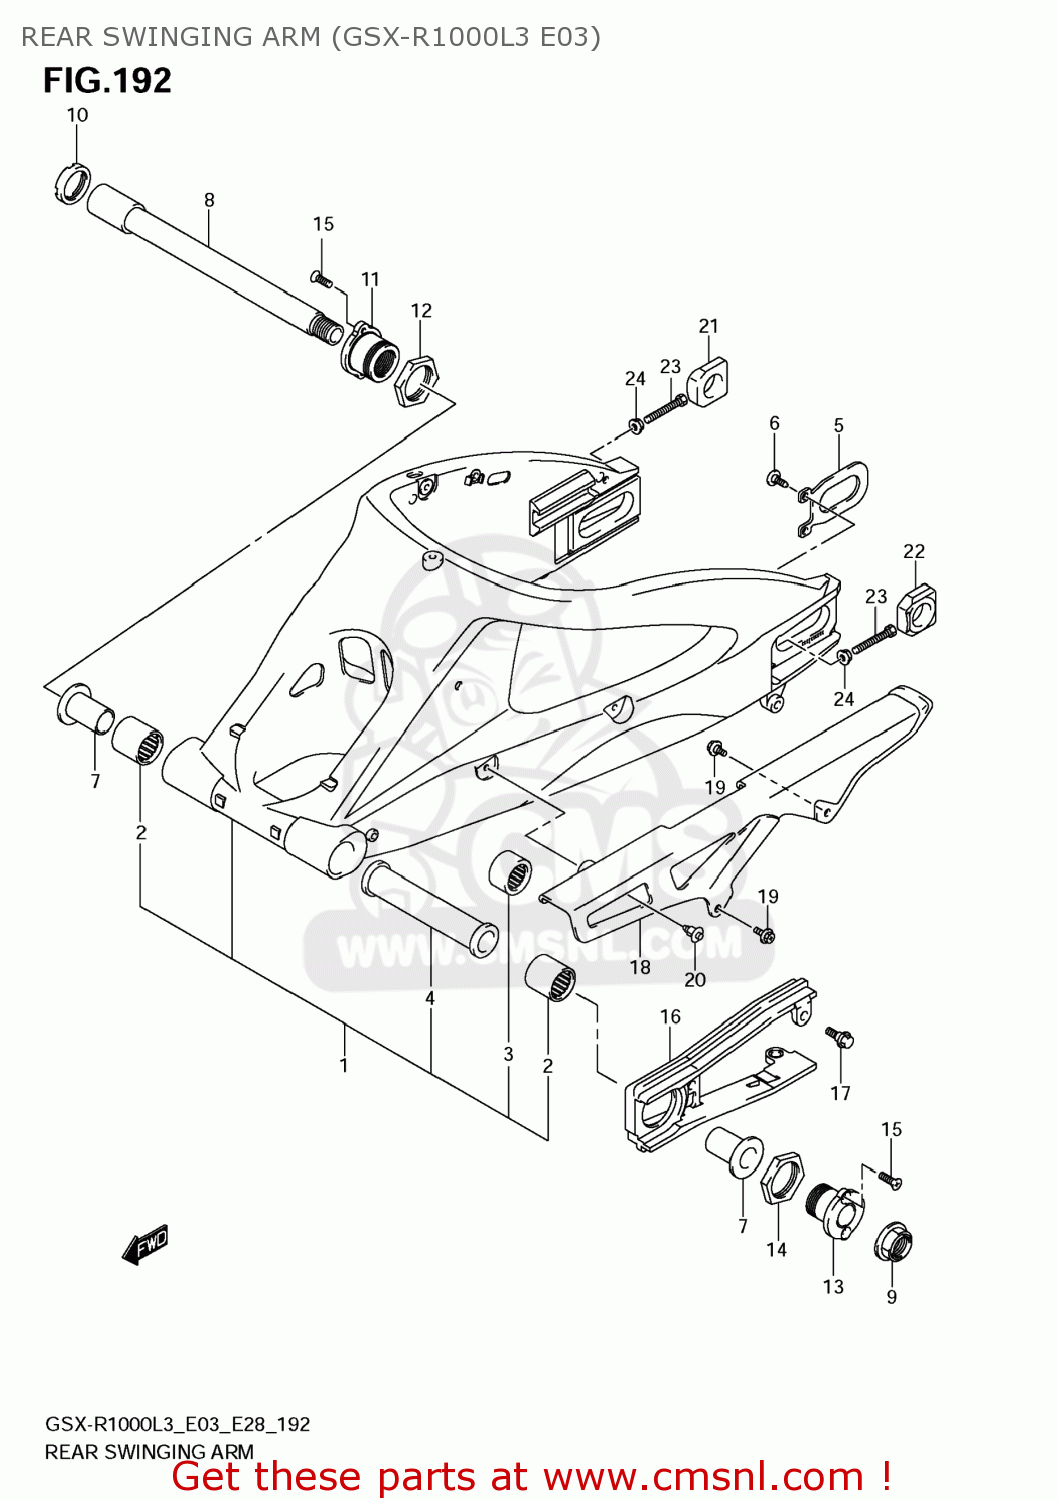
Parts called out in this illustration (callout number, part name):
1	SWINGINGARM ASSY,RR
2	BEARING(27X35X35)
3	BEARING(20X27X30)
4	SPACER,RR SWG PVT CTR
5	PLATE,RR SWING ARM BRKT
6	SCREW(6X12)
7	SPACER,RR SWGARM PIVOT BEARING
8	SHAFT,RR SWINGINGARM PIVOT
9	NUT
10	NUT,RR SWGARM PIVOT BOLT
11	BOSS,RR SWINGINGARM PIVOT,R
12	NUT,RR SWGARM PIVOT BOSS,R
13	BOSS,RR SWINGINGARM PIVOT,L
14	NUT,RR SWGARM PIVOT BOSS,L
15	SCREW
16	BUFFER,CHAIN TOUCH DEFENSE
17	BOLT(6X17.8)
18	CASE,CHAIN
19	BOLT(6X12)
20	CLIP(BLACK)
21	ADJUSTER,CHAIN
22	ADJUSTER,CHAIN
23	BOLT(8X50)
24	NUT
